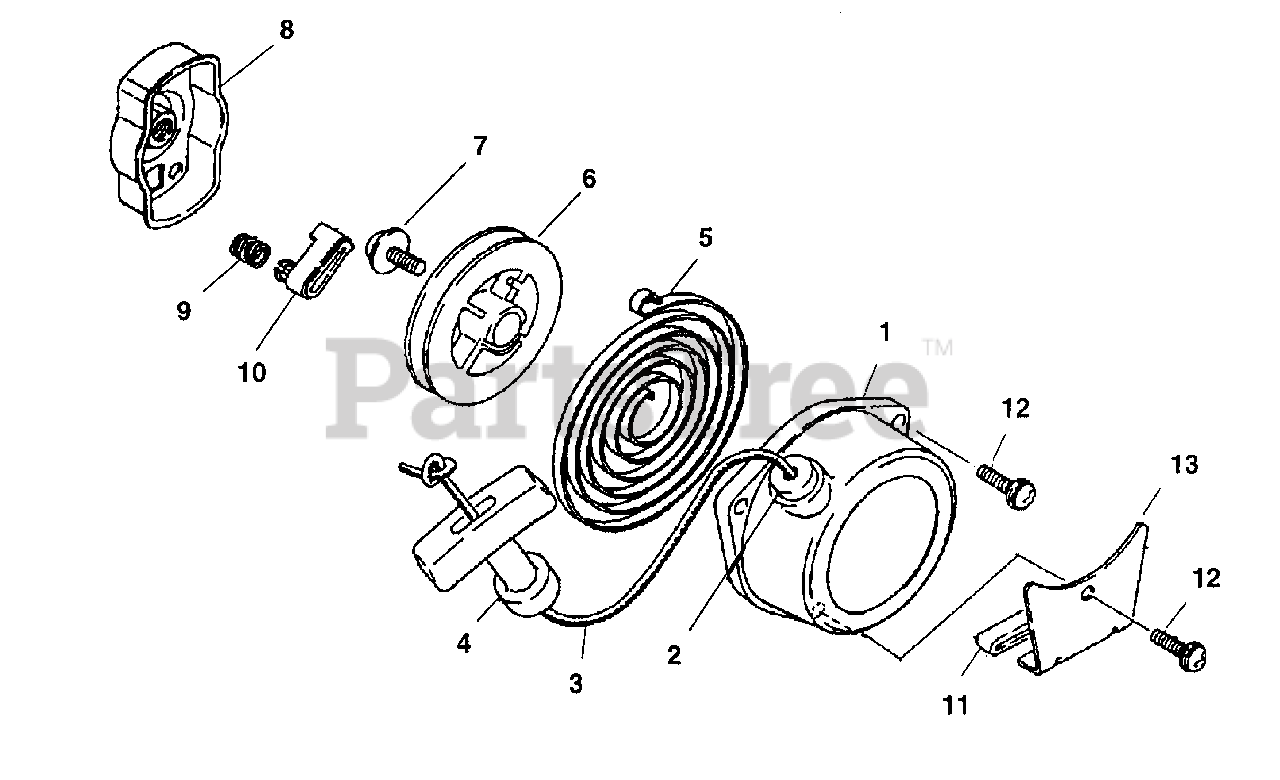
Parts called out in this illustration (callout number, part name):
1	STARTER ASSY.
3	ROPE, STARTER
4	KNOB, STARTER
5	SPRING, REWIND
7	SCREW & WASHER
8	PULLEY ASSY., STARTER
9	SPRING, RETURN
10	RATCHET
12	SCREW & WASHER
13	BRACKET
